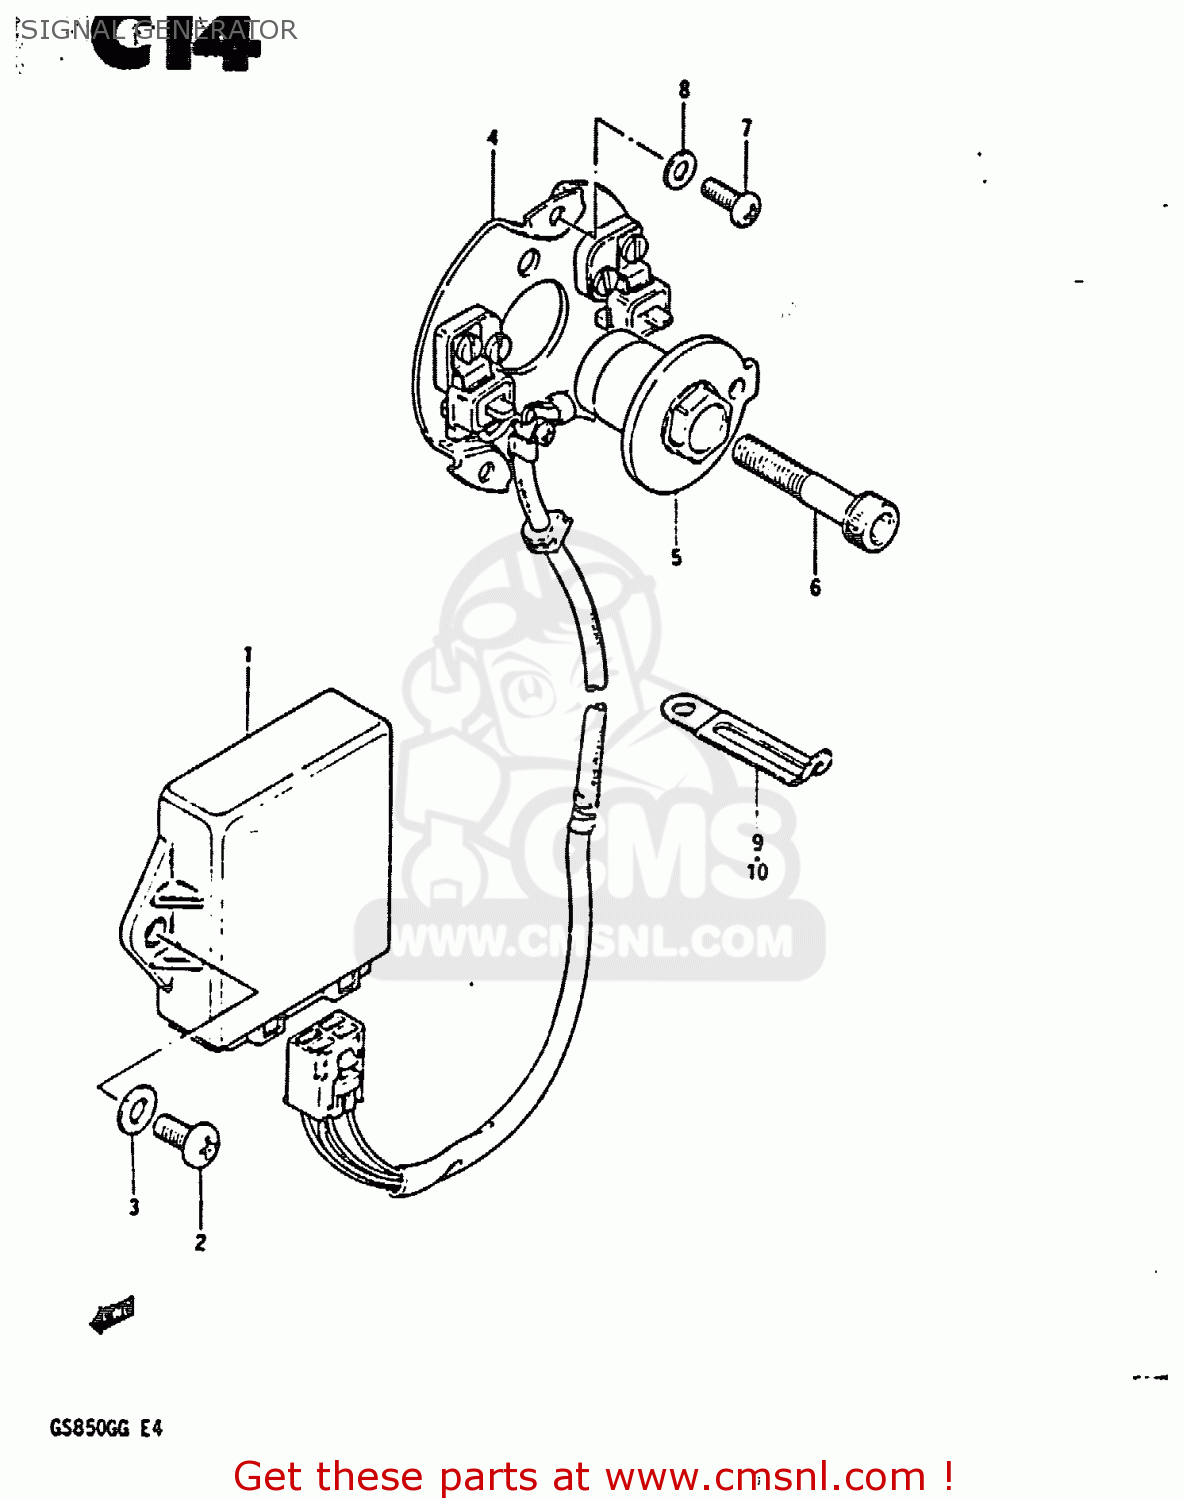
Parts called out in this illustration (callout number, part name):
1	IGNITOR UNIT,ESA
2	SCREW 6X12
3	WASHER
4	STATOR,SIGNAL GENERATOR
5	GOVERNOR ASSEMBLY
6	BOLT
7	SCREW(5X12)
8	WASHER(5.5X10X0.8)
9	CLAMP L:35
10	CLAMP
